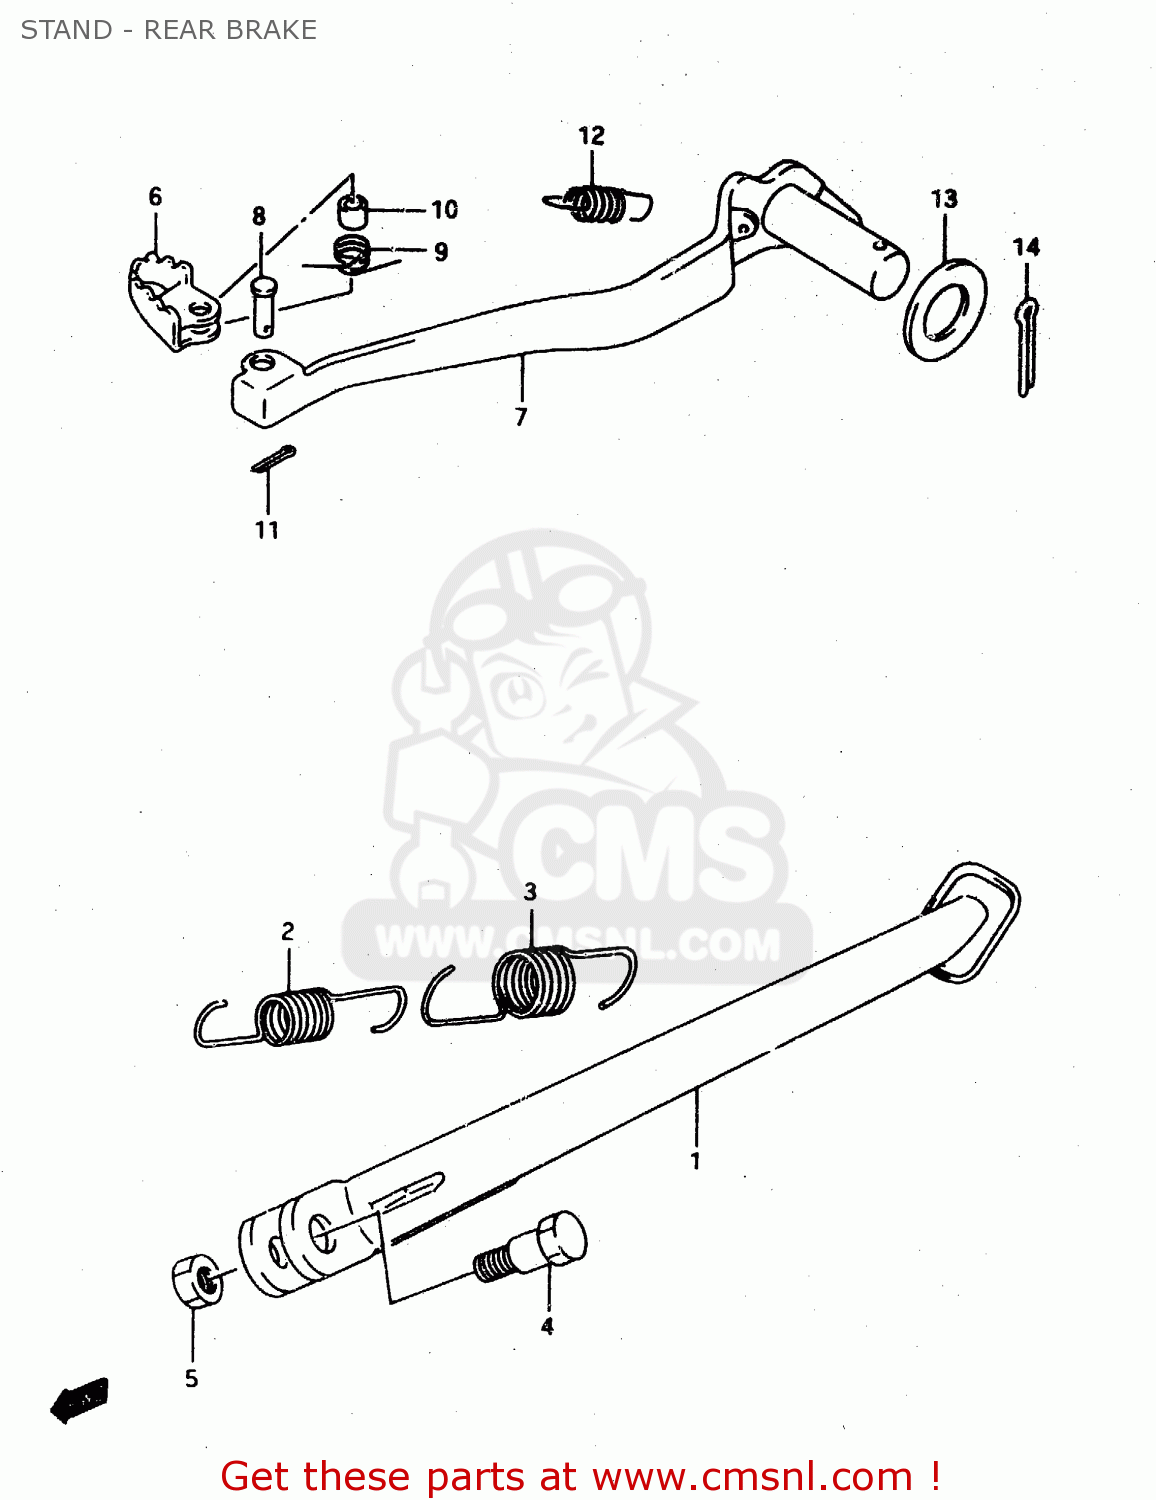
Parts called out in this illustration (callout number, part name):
1	STAND,PROP(BLACK)
2	SPRING
3	SPRING
4	BOLT(10X30)
5	NUT
6	PEDAL,BRAKE
7	ARM,BRAKE PEDAL
8	PIN
9	SPRING
10	SPACER (6.6X9X6.5)
11	PIN
12	SPRING
13	WASHER (17.5X34X2)
14	COTTER PIN
